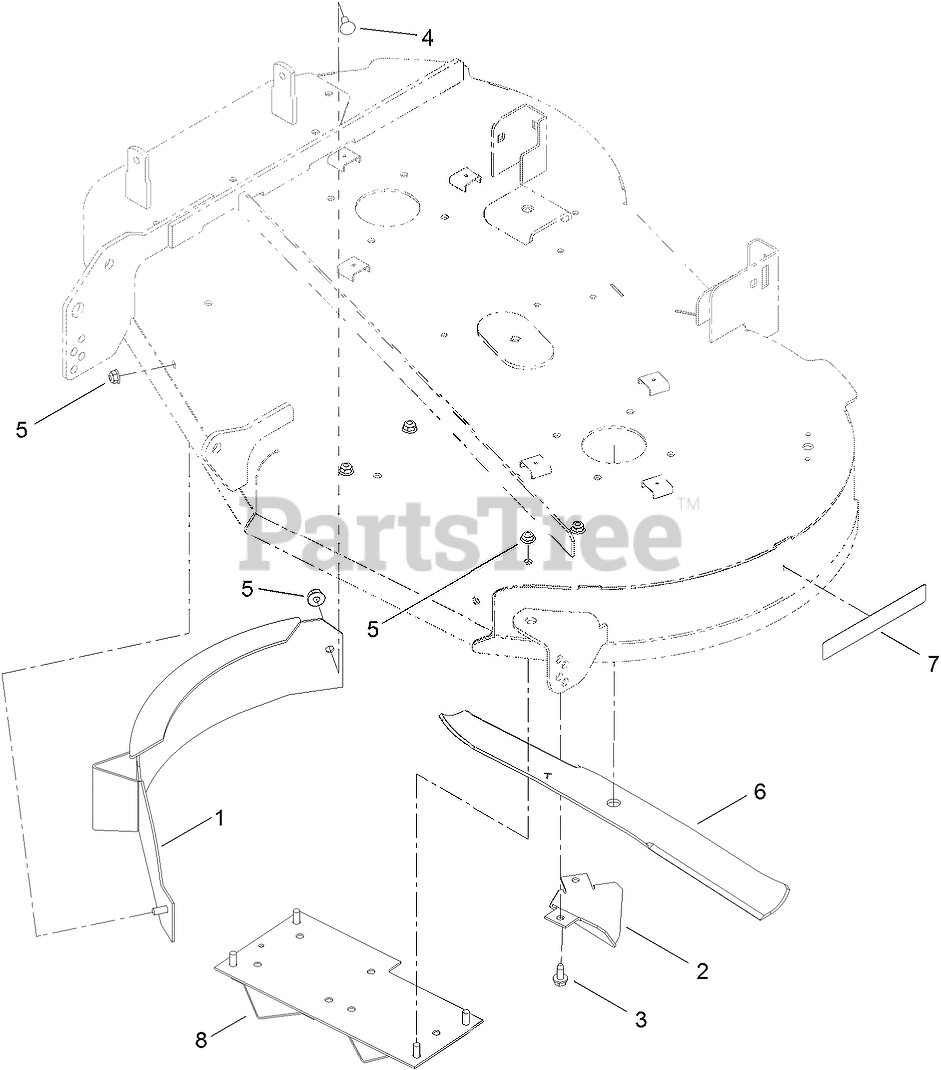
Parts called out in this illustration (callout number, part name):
1	BAFFLE ASM
2	KICKER-FLANGED
3	SCREW-HWHTF
4	BOLT-CARR
5	NUT-HF, NI
7	DECAL-RECYCLER
8	KICKER ASM
